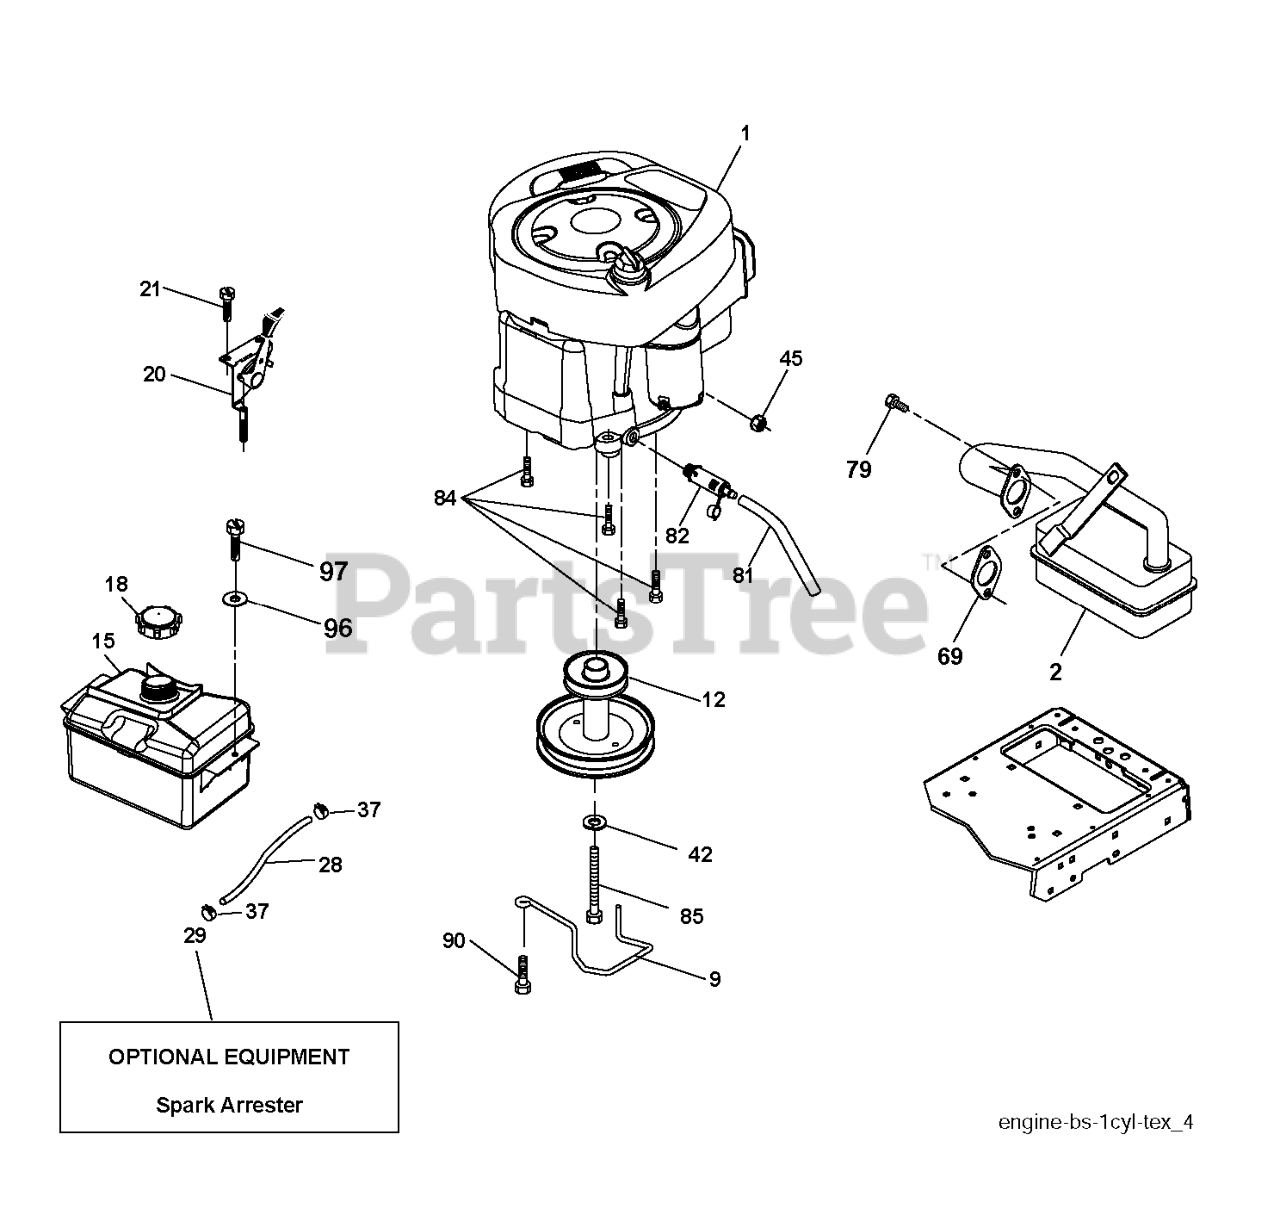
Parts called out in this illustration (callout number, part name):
2	MUFFLER.B&S.MODEL.21.11HP.OHV
9	KEEPER.BELT.ENGINE.3.25 (3 2)
12	PULLEY.ENG.CL.MECH.SLVR.LT/YT
15	RP TANK FUEL FRT 1.5 GAL
18	FUEL CAP
20	CONTROL.TH/CK.C.
21	SCREW.#10 X 0.750.BOS
28	LINE.FUEL.20
29	KIT.SPARK ARRESTOR 794945 B&S
37	HOSE CLAMP
42	LOCKWASHER
45	NUT
69	REPL BY 532 27 22-93
79	SCREW.SOCKET HD.5/16-1
81	TUBE, DRAIN OIL ASM.
82	PLUG DRAIN OIL EASY
84	SCREW.3/8-16
85	BOLT HEX 7/16-20X4-1/4"
90	SCREW 3/8-16X1
97	SCREW HEXWSHR 1/4-20X3/4
